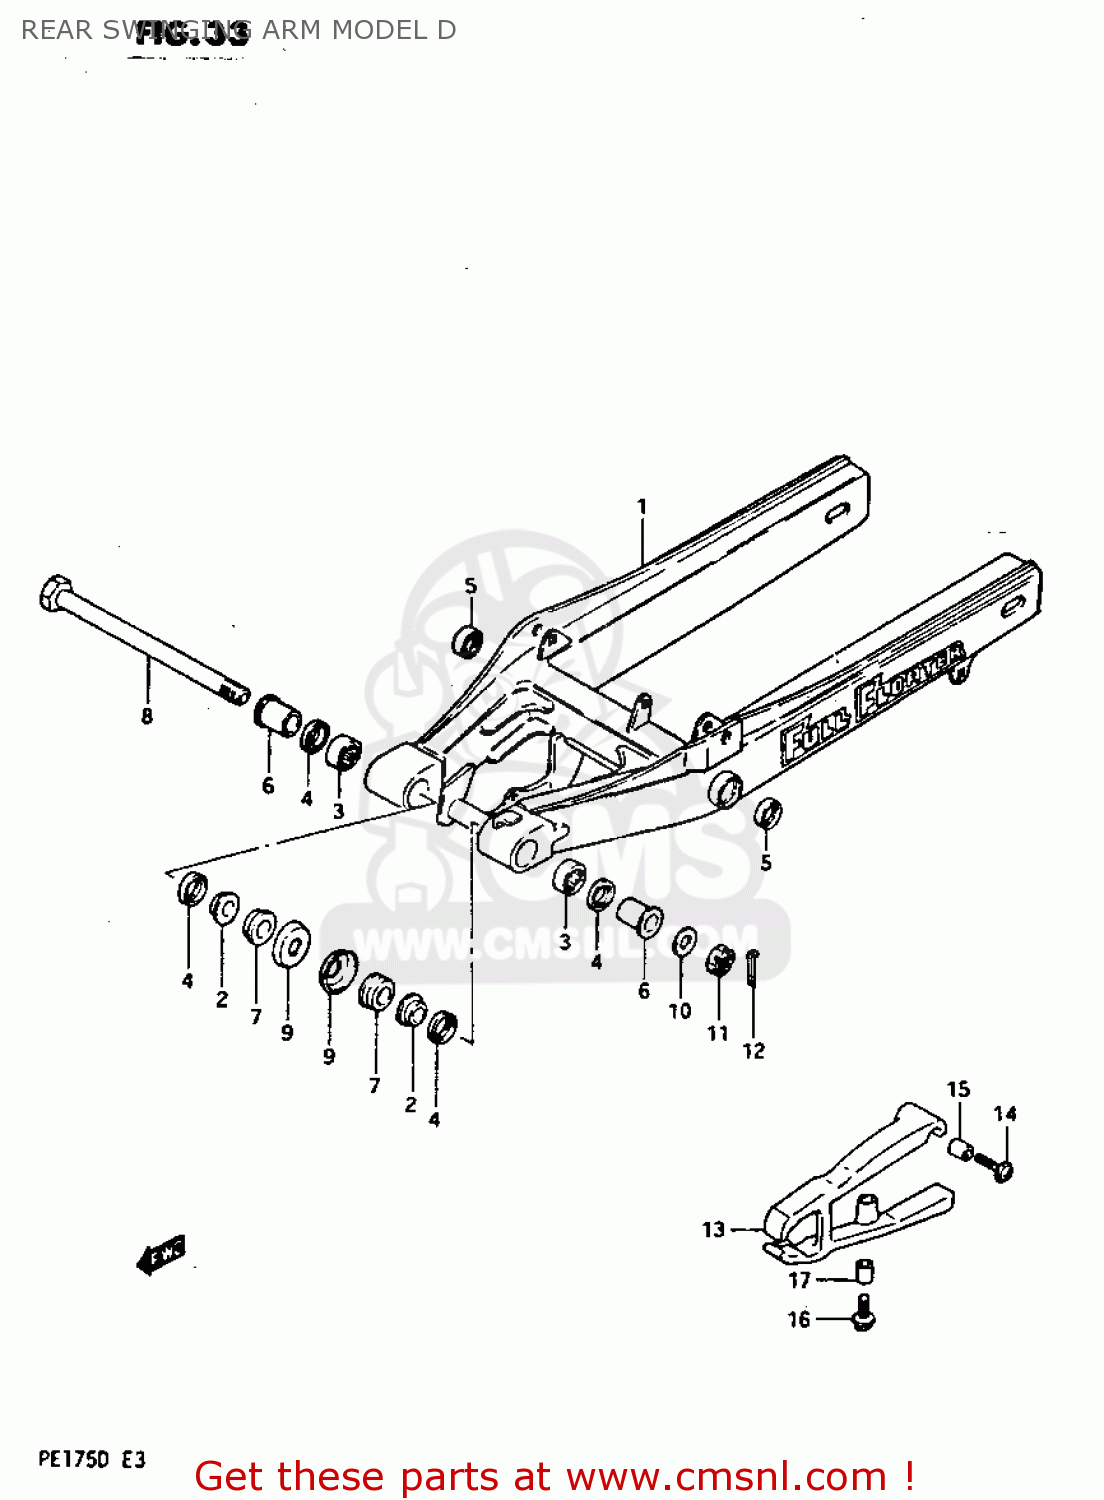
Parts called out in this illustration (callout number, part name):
1	SWING ARM ASSEMBLY,REAR
2	BUSH,RR SWINGINGARM PIVOT
3	BEARING(20X27X20)
4	OIL SEAL
5	OIL SEAL
6	SPACER,RR SWGARM PIVOT
7	SPACER,RR SWGARM PIVOT INNER
8	SHAFT,RR SWINGINGARM PIVOT
9	COVER,RR SWGARM DUST SEAL
10	WASHER
11	NUT 14MM
12	COTTER PIN
13	BUFFER,CHAIN TOUCH DEFENSE
14	BOLT,CHAIN TOUCH DEFEND
15	SPACER (6.1X9X9)
16	BOLT,CHAIN TOUCH DEFEND
17	SPACER(6.5X10.5X22.5)
